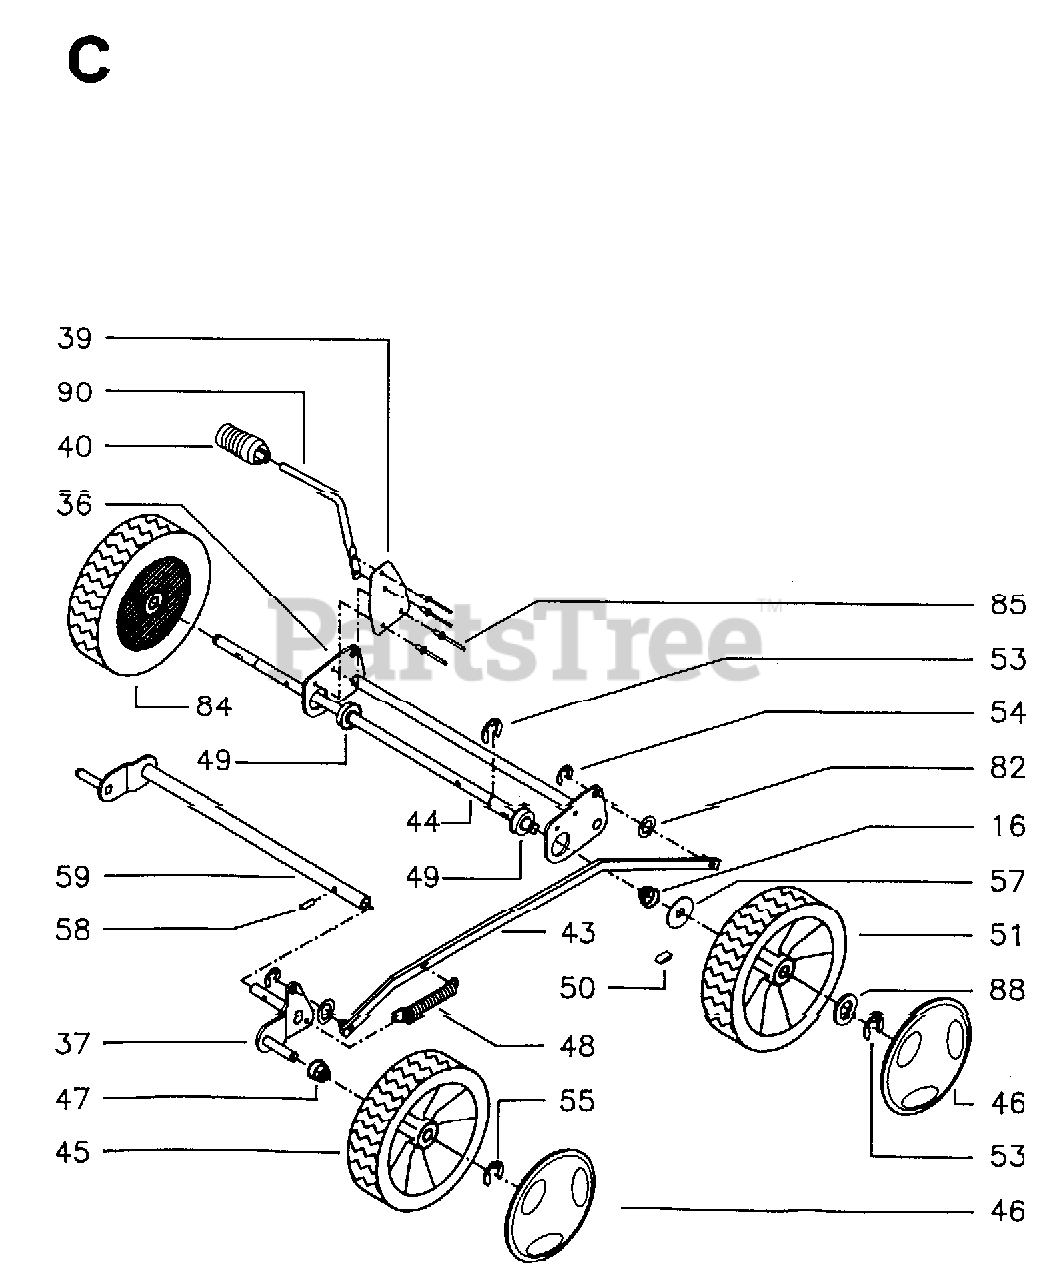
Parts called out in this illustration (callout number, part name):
47	CONE SPRING
50	CARRIER
53	SNAP RING
55	SNAP RING
